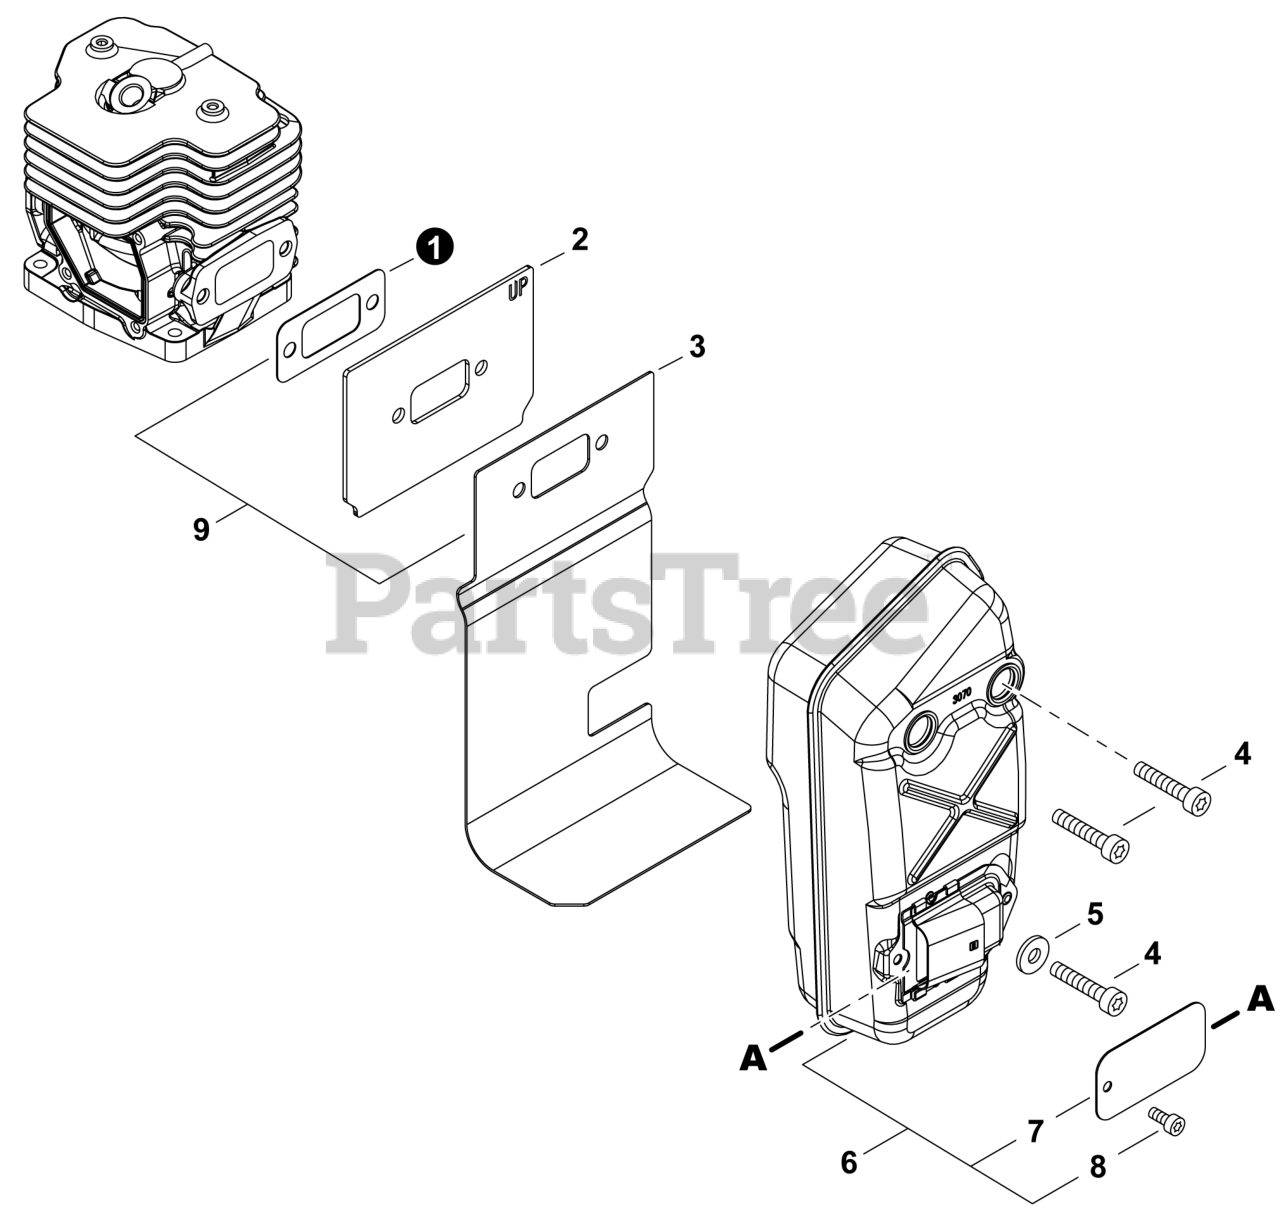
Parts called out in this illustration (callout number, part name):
1	GASKET, EXHAUST
2	PLATE, EXHAUST
3	HEAT SHIELD, EXHAUST
4	BOLT, TORX 6x20
6	MUFFLER ASSY
7	SCREEN, SPARK ARRESTER
8	BOLT, TORX 4x8
9	GASKET KIT: ENGINE, INTAKE, EXHAUST
